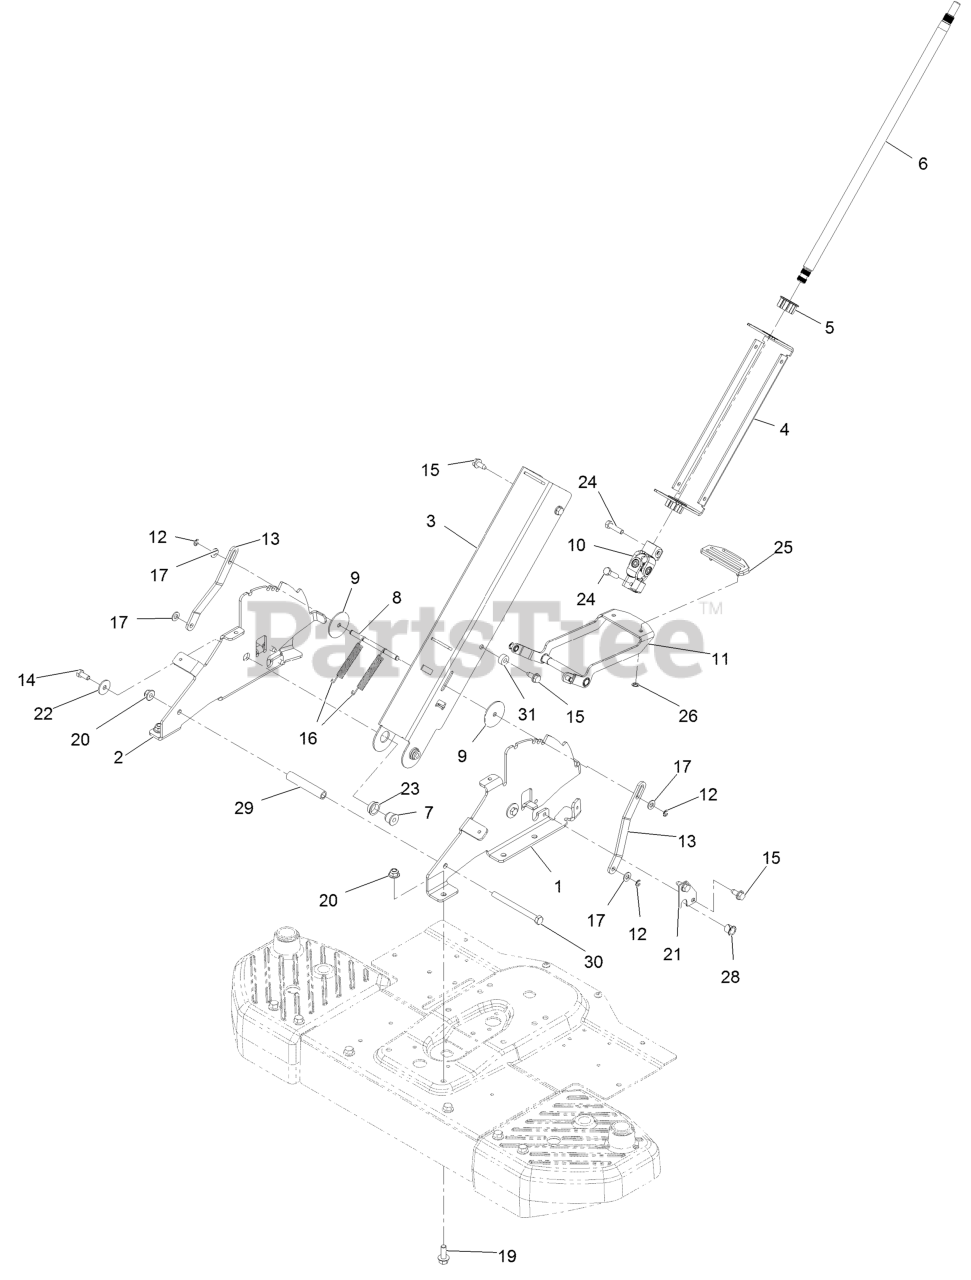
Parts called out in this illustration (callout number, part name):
1	BRACKET-PIVOT, COLUMN (LH
2	BRACKET-PIVOT, COLUMN (RH
3	COLUMN-FRONT
4	COLUMN-BACK
5	BUSHING-STEERING, UPPER
6	SHAFT-STEERING, UPPER
7	SPACER-PIVOT, COLUMN
8	ROD-PLUNGER
9	WASHER-SHAFT, TILT
10	U-JOINT ASM
11	RELEASE PEDAL ASM
12	E-RING
13	PLATE-PLUNGER
14	SCREW-HH
15	Screw-HWH 5/16-18 X 3/4 Tf
16	SPRING-EXTENSION
17	WASHER-PLAIN
19	SCREW-HHF
20	NUT-HF, NI
21	PLATE-RETAINER
22	WASHER-PIVOT
23	BUSHING-FLANGE
24	SCREW-HH
25	PAD-TILT PEDAL
26	NUT-PUSH
28	BUSHING-NYLINER
30	SCREW-HH
